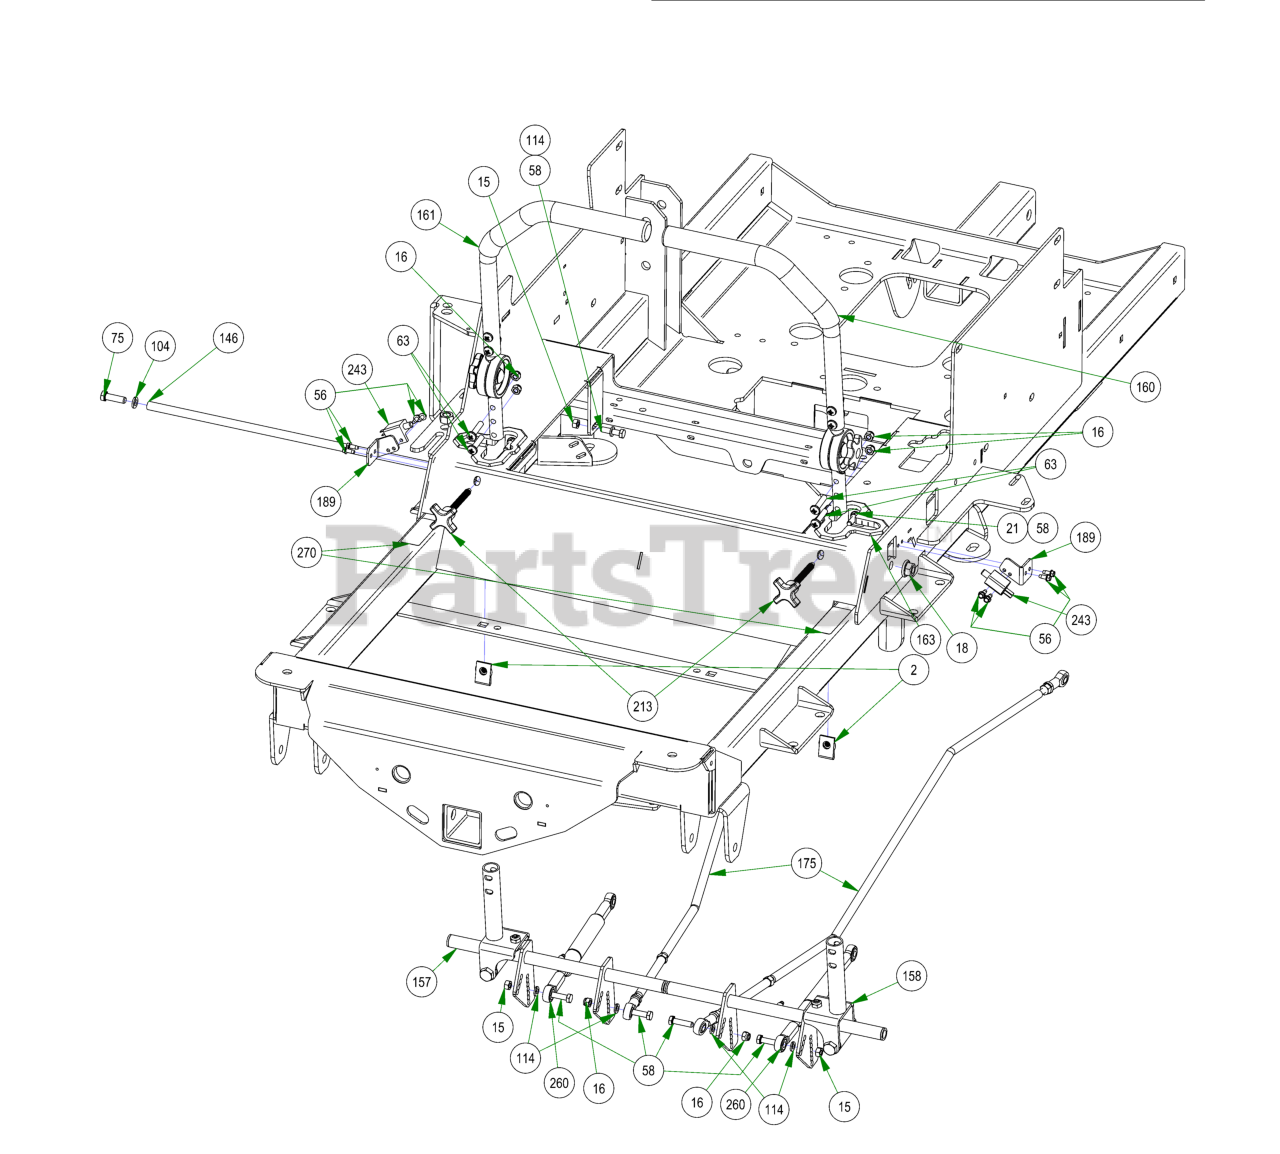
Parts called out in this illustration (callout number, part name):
2	Extruded Nut 3/8"-16 3/4" Hole Center With Patch
15	5/16-18 HEX NUT ZINC
16	5/16-18 NYL INS L/N ZC
18	1/2-13 NYLON INSERT FLANGE LOCKNUT ZINC
21	5/16-18 HEX SERRATED FLANGE NUT HARD/ZINC
56	12-24 X 1/2 HEX WASHER UNLSOT F TCS ZINC
58	5/16-18 X 1-1/4 HEX C/S (GR.5) ZC
63	5/16-18 x 1 3/8" Futton Head Torx Drive Bolt
75	3/8-16 X 1-1/4 HEX CAP SCREW (GR.5) ZINC
104	3/8 SPLIT LOCKWASHER ZINC
114	5/16 SPLIT LOCKWASHER ZINC
146	2019 Steering Actuator Rod
157	2019 R Series RH Arm Rod Assembly
158	2019 R Series LH Arm Rod Assembly
160	2019 Left Hand ADJ. Steering Arm Kit
161	2019 Right Hand ADJ. Steering Arm Kit
163	Snap-in Drive Arm Bushing
175	2019 Renegade Push Rod Assembly
189	2019 Arm Switch Bracket
213	Speed Limiting Knob 3/8-16X 3"
234	2022 Horizontal Diesel Frame
243	Safety Switch
260	2019 SROID Damper With Spherical Rod Ends
270	2018 LH/RH Steering Control Decal Roll
